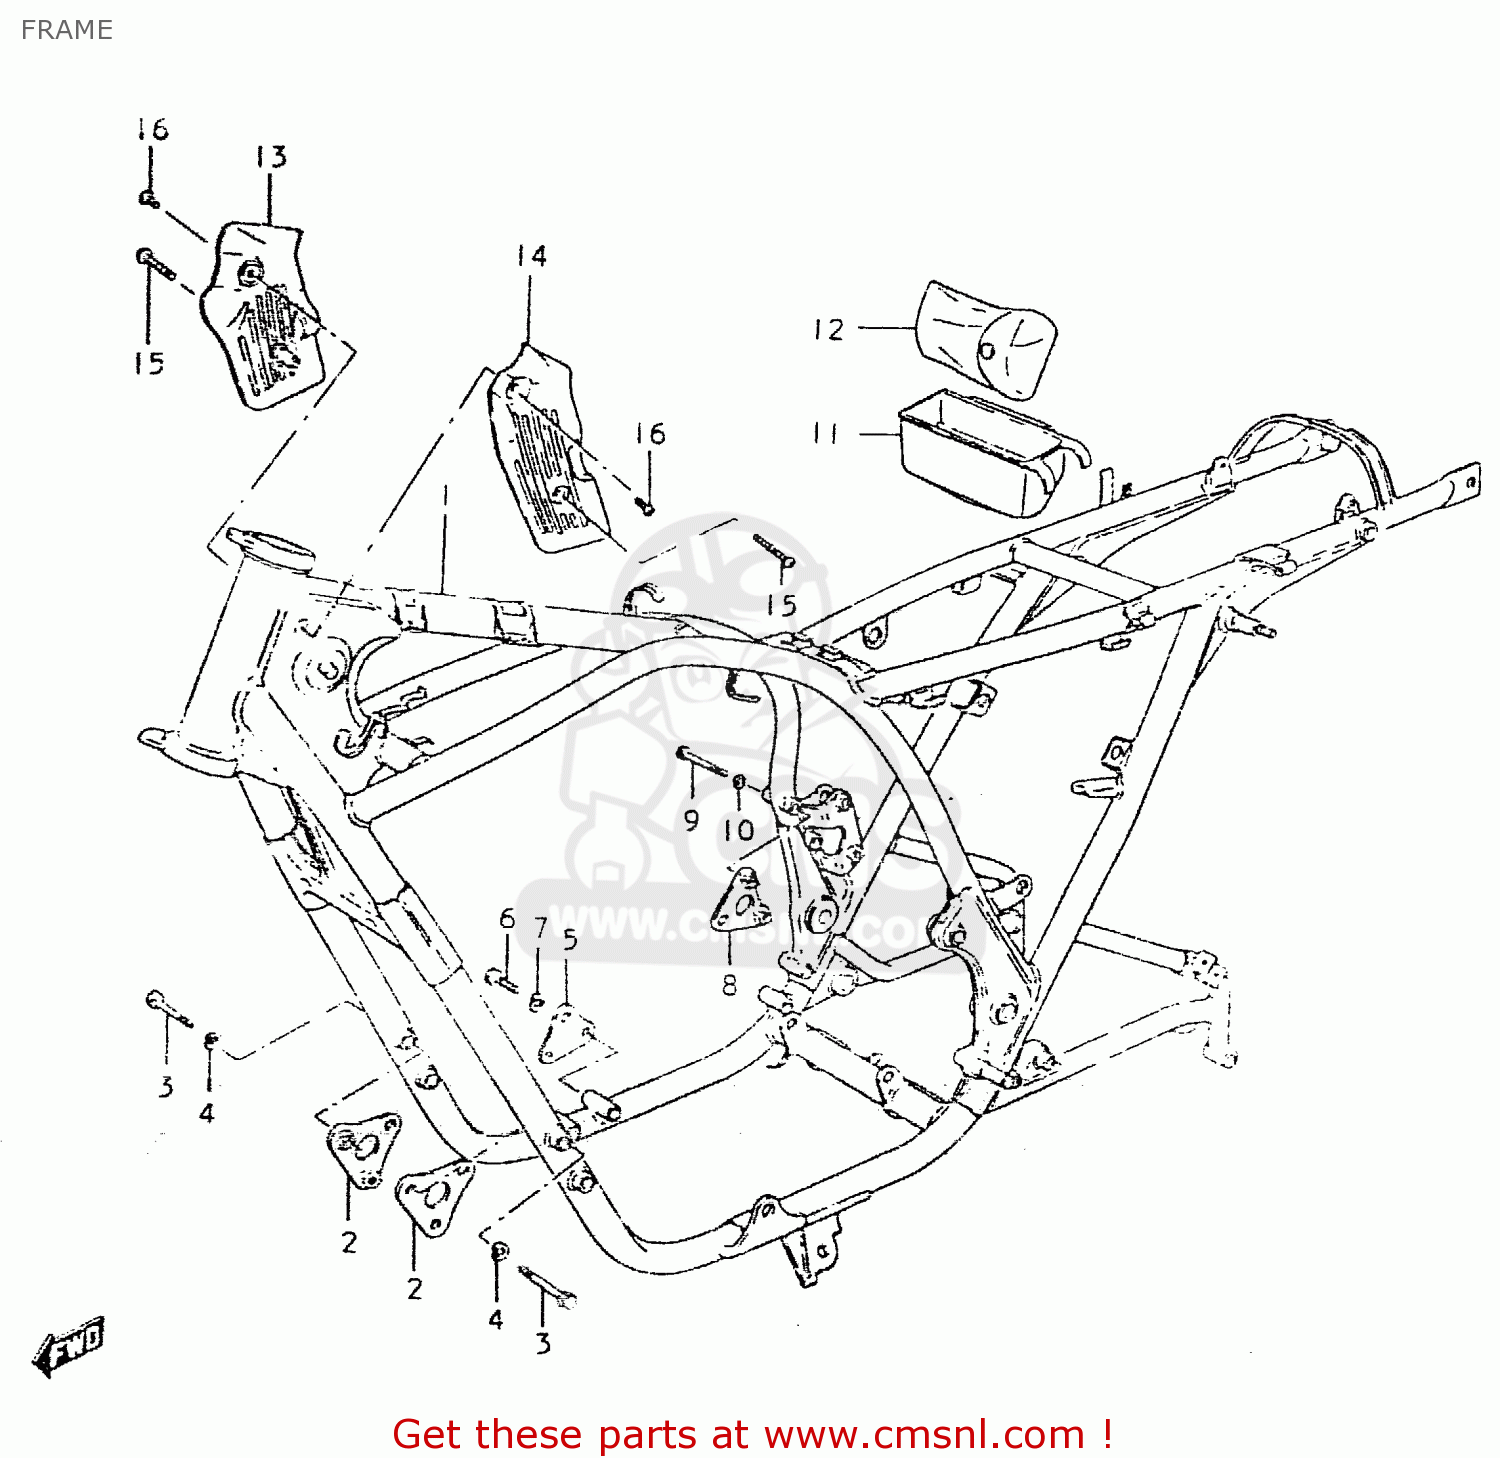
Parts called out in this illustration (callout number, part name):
1	FRAME
2	PLATE,ENGINE MOUNTING
3	BOLT
4	LOCK WASHER
5	PLATE,ENGINE MOUNTING
6	BOLT
7	LOCK WASHER
8	PLATE,ENGINE MOUNTING
9	BOLT 8X55
10	LOCK WASHER
11	HOLDER,TOOL
12	TOOL ASSY
13	COVER,FRAME HEAD,RIGHT
14	COVER,FRAME HEAD,LEFT
15	SCREW, LOWER
16	SCREW
